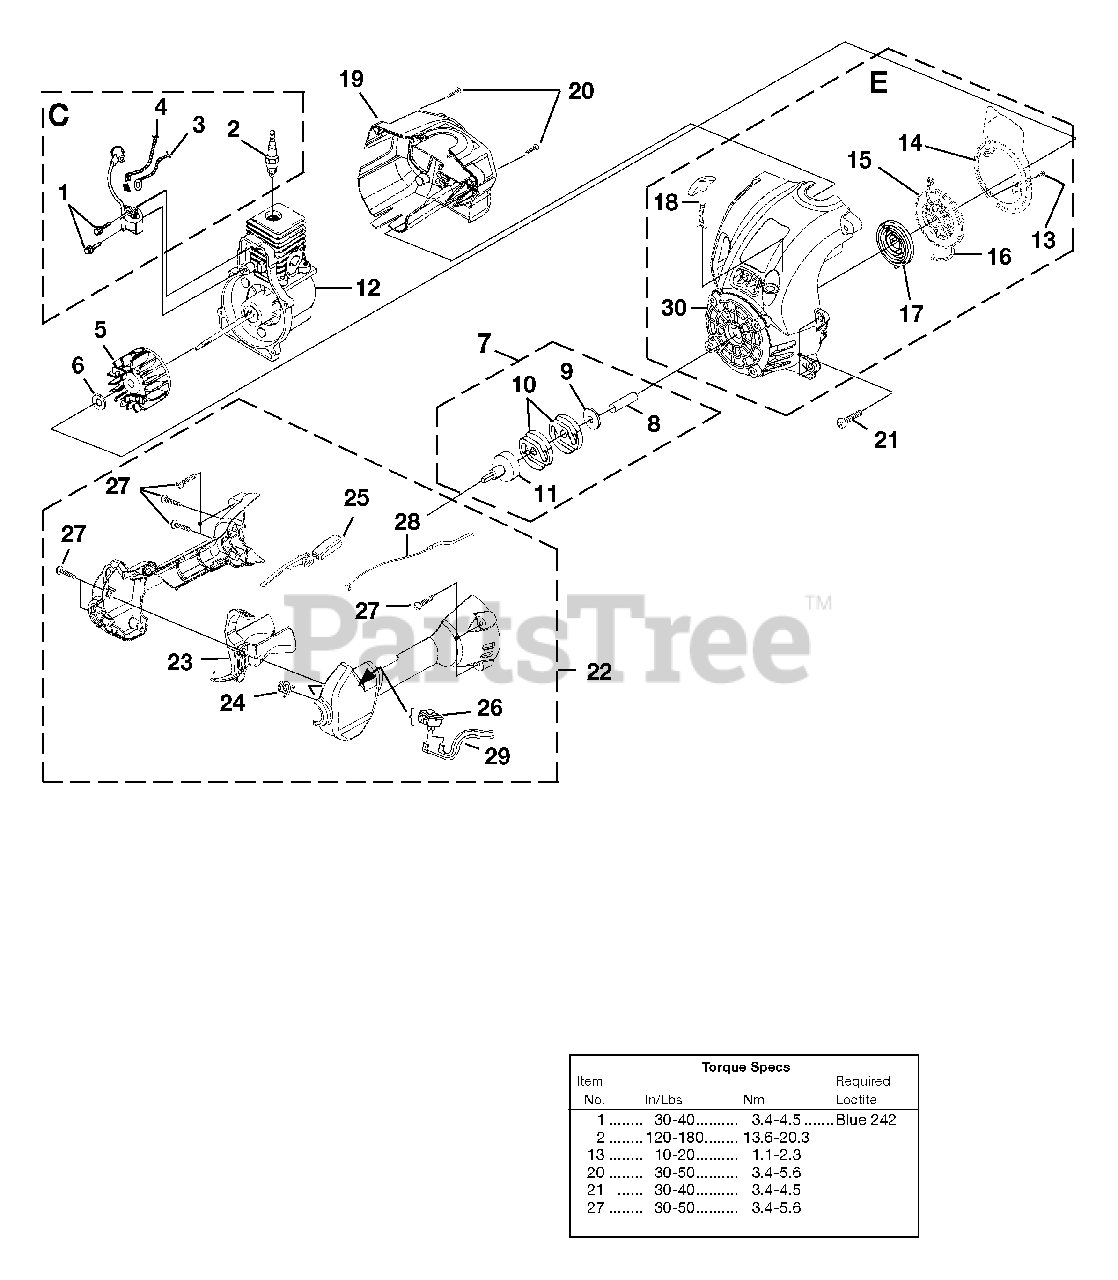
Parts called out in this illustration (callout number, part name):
1	SCREW-Taptite (8-32 X 1")
2	SPARK PLUG
3	LEAD-Electrical
4	LEAD-Electrical
6	WASHER-Flat
7	CLUTCH AND DRUM KIT
8	SPACER
9	WASHER-Flat
11	CONNECTOR AND DRUM
12	SHORT BLOCK
13	SCREW-Thread Form (8-16 X 1/2")
14	BAFFLE-Air
15	PULLEY-Starter
16	ROPE-Starter (42")
17	SPRING & CONTAINER
18	GRIP-Starter
19	HOUSING-Rear
20	SCREW-Plastite (10-14 X 7/8")
21	SCREW-Taptite (10-24 X 3/4")
22	CONTROL HANDLE ASSY.
23	TRIGGER-Throttle
25	THROTTLE INTERLOCK
27	SCREW-Taptite (10-14 X 1")
28	CABLE-Throttle
29	LEAD-Electrical
30	Starter Housing W/Eyelet
C	IGNITION KIT
E	COMPLETE STARTER ASSEMBLY
